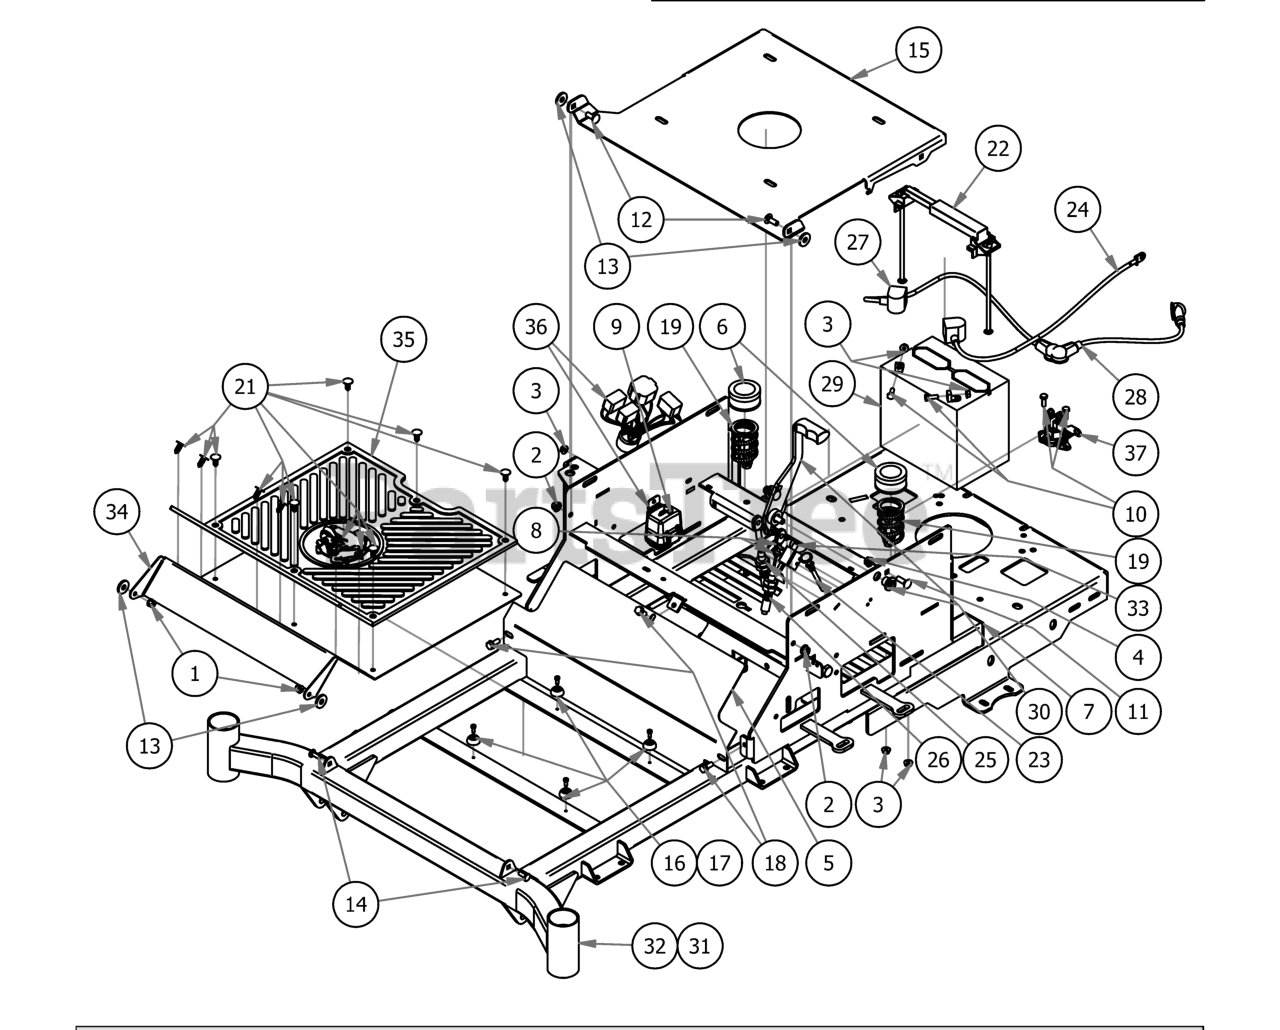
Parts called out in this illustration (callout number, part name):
1	1/4-20 Nylon Insert flange Nut
2	5/16" Nylon Flange Nut
3	1/4-20 Hex Flange Nuts Zinc w/Serrations
4	5/16" Flange Nut
5	2017 ZT Cooler Cover
6	Seat Spring Cap Cover
7	2x2 Square Plug
8	12-24x 1/2 HWH Bolt
9	1/4" x 1/2" BS C/S 18-8 SS
10	1/4" x 3/4" Hex Bolt
11	5/16" x 1" Carriage Bolt
12	5/16" x 7/8" Carriage Bolt
13	.360 ID Plastic Washer
14	1/4" x 3/4" Carriage Bolt
15	Seat Plate 2016
16	Button Bumper
17	#10 x 1/2" Self Tapping Screw
18	5/16 x 3/4 washer head type F screw
19	Seat Spring Assembly
21	Ratchet Fastener
22	Hold Down Assembly
24	Ground Cable
25	Brake Cable,18.5"
26	Brake Cable, 24.5"
27	24" Red Battery Cable
28	12" Red Battery Cable
30	2017 ZT Brake Handle Assembly
31	ZT 54" and 60" Frame
32	2017 MZ/ZT 42"-48" Frame
33	Safety Switch
34	MZ/ZT 2017 Floorboard
35	2017 MZ/ZT Floor Mat
36	Wiring Harness
